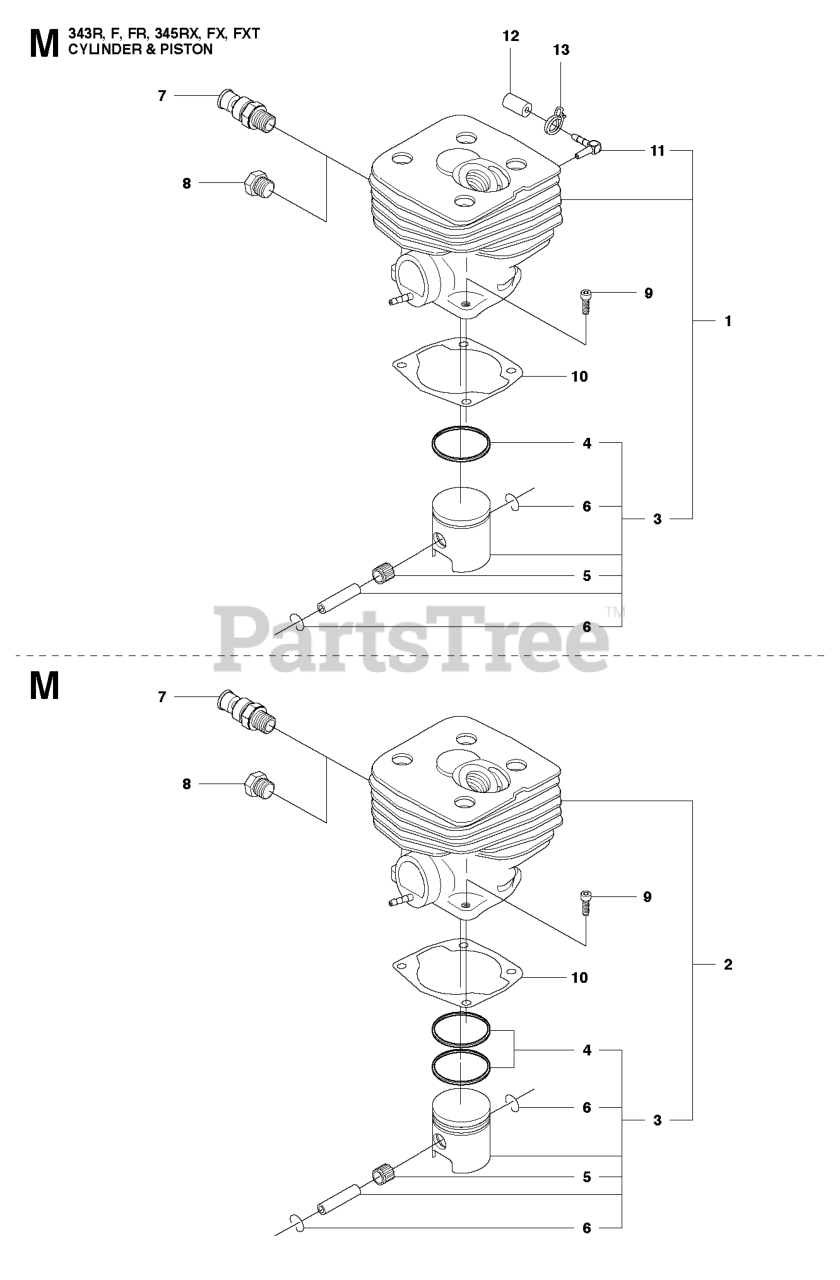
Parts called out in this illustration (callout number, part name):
1	CYLINDER
2	CYLINDER ASSY
3	RP PISTON ASSY
3	PISTON ASSEMBLY
4	PISTON RING
5	SUPPORT BUSHING
6	LOCKING RING
7	DECOMPRESSION VALVE
8	CYLINDER PLUG
9	SCREW MC6S 5X20
10	GASKET
11	NIPPLE
12	PROTECTIVE CAP
13	CLAMP
